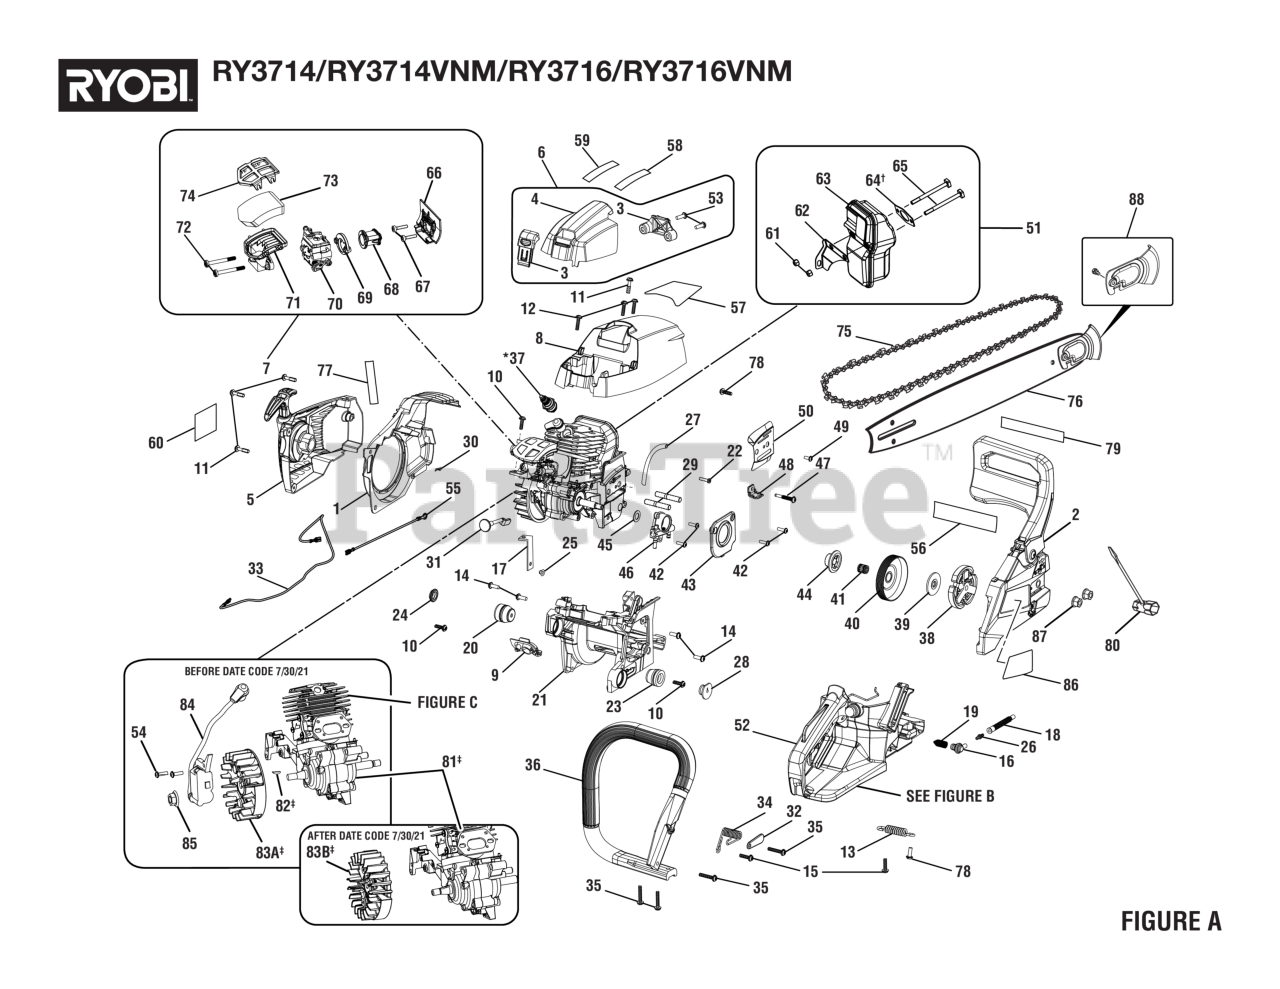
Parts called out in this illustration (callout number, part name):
1	Cylinder Baffle
2	Clutch Cover Assembly
3	Carburetor Cover Latch and Bracket Assembly
4	Carburetor Cover Housing
5	Starter Housing Assembly
6	Carburetor Cover Assembly
7	Intake Assembly
8	Cylinder Housing Assembly
9	Throttle Rod Grommet
10	Screw (M5 x 16 mm, T25 Torx Pan Hd.)
11	Screw, Truss Hd., Plastite (10-14 x 7/8")
12	Screw (M5 x 14 mm, T25 Torx Pan Hd.)
13	Damper Spring
14	Screw (M5 x 16 mm, T25 Torx Pan Hd.)
15	Screw (M5 x 14 mm, T25 Torx Pan Hd.)
16	Oil Filter Grommet
17	Band Stopper
18	Rubber, Pipe In Oil Pump
19	Cone Spring
20	Rubber Damper
21	Engine Case
22	Pin (Oil Pump Outlet)
23	Damper Rubber
24	Damper Cap.
25	Starter Case
26	Joint For Pipe In Comp
27	Oil Pump Rubber Tube (Outlet)
28	Damper Cap (T)
29	Bar Stud (5/16-18 x 23.5 mm / 5/16-18 x 18 mm)
30	Spring Clip (Choke Rod)
31	Choke Rod
32	Damper Plate
33	Lead Wire Assembly (Red)
34	Damper Spring
35	Screw (M5 x 27 mm, T25 Torx Pan Hd.)
36	Front Handle
37	Spark Plug (Champion RCJ6Y)
38	Clutch Assembly
39	Thrust Plate
40	Clutch Drum
41	Clutch Drum Needle Bearing
42	Screw (M4 x 14 mm, T20 Torx Pan Hd.)
43	Oil Pump Cover
44	Oil Pump Drive Gear
45	Washer (Oil Pump Drive Gear)
47	Screw (M4 x 33 mm, T25 Torx Pan Hd.)
48	Chain Catcher.
49	Screw (M4 x 12 mm, T20 Torx Pan Hd.)
50	Chain Guard Plate.
51	Exhaust Assembly.
52	Chassis & Handle Components
53	Screw (M4 x 10 mm, T20 Torx Pan Hd.)
54	Screw (M4 x 14 mm, T20 Torx Pan Hd.)
55	Lead Wire Assembly (Black)
56	Chain Brake Label (RY3716)
57	Warning Label
58	Starting Label (Right)
59	Starting Label (Left)
60	Starting House Label (R3716)
61	Hex Nut (M5, Muffler)
62	Muffler Bracket
64	Gasket (Muffler)
65	Bolt (Muffler, M5 x 62 mm)
67	Bolt (M9 x 19 mm, T25 Torx Pan Hd.)
68	Intake Boot
69	Intake Bracket
70	Carburetor Assembly
71	Air Box Base
72	Screw (M5 x 44 mm,T25 Torx Hd. Carburetor)
73	Foam Air Filter
74	Air Filter Retainer
75	16 in. Chain (RY3716, 56 Drive Link)
76	16 in. Guide Bar Assembly (RY3716)
77	Warning Label (Combustion)
78	Screw (M5 x 0.8 mm, T25 Torx Pan Hd.)
79	Pull To Release Brake Label
80	Combination Wrench
81	Short Block
82	WOODRUFF KEY (10 mm X 3 mm)
83A	Flywheel Assembly (B.D.C. 7/30/21)
83B	Flywheel Assembly (A.D.C. 7/30/21)
84	Ignition Assembly
85	Flange Nut (M8, Flywheel)
86	Bar Cover Label
87	Hex Nut (5/16-18 Flange)
88	Bar Nose Kit
